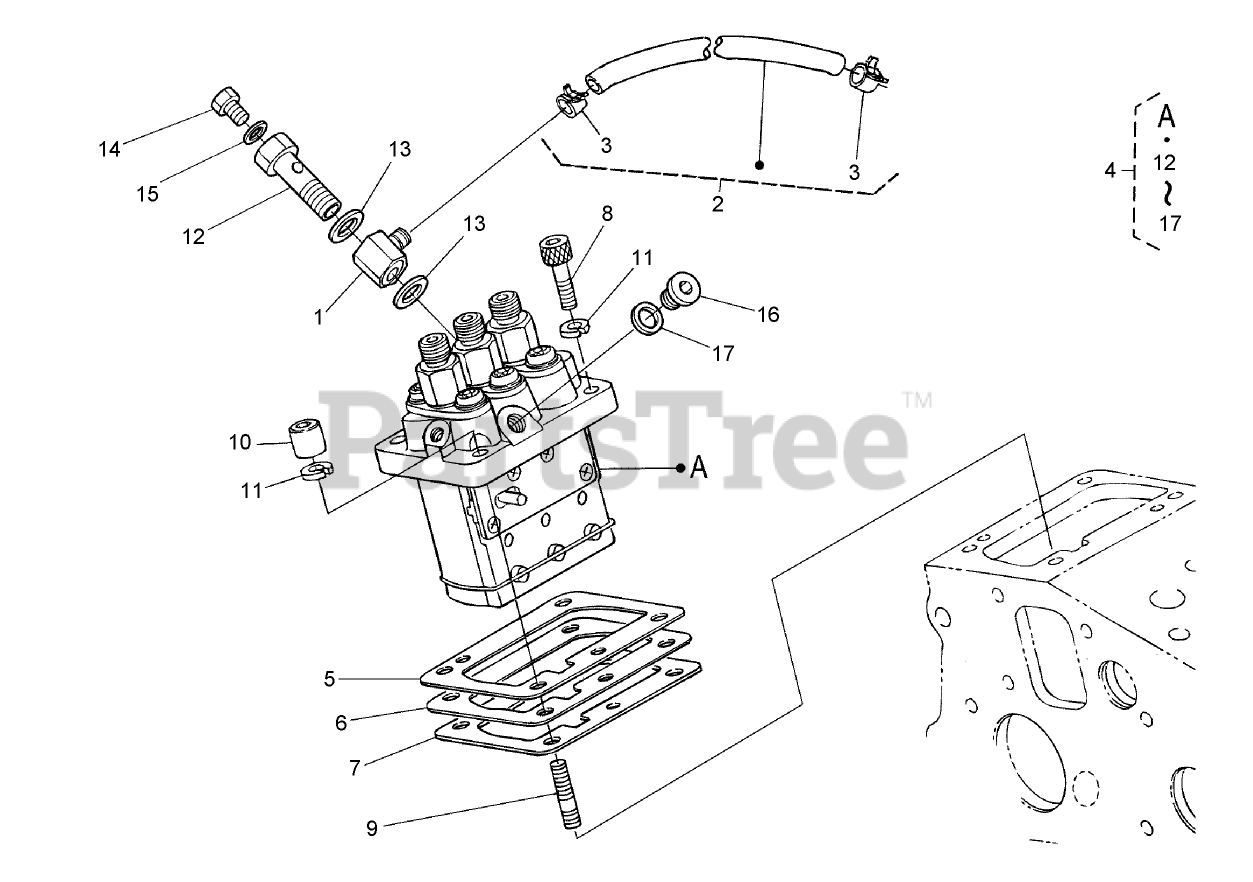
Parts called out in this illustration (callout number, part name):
1	JOINT-EYE
2	FUEL PIPE ASM
3	CLIP-PIPE
4	INJECTION PUMP ASM
5	SHIM-INJECTION (0.20MM)
6	SHIM-INJECTION (0.25MM)
7	SHIM-INJECTION (0.30MM)
8	BOLT-HSH
10	NUT-CAP
11	WASHER-SPRING
12	SCREW-HOLLOW
13	GASKET
14	SCREW
15	GASKET
17	GASKET
